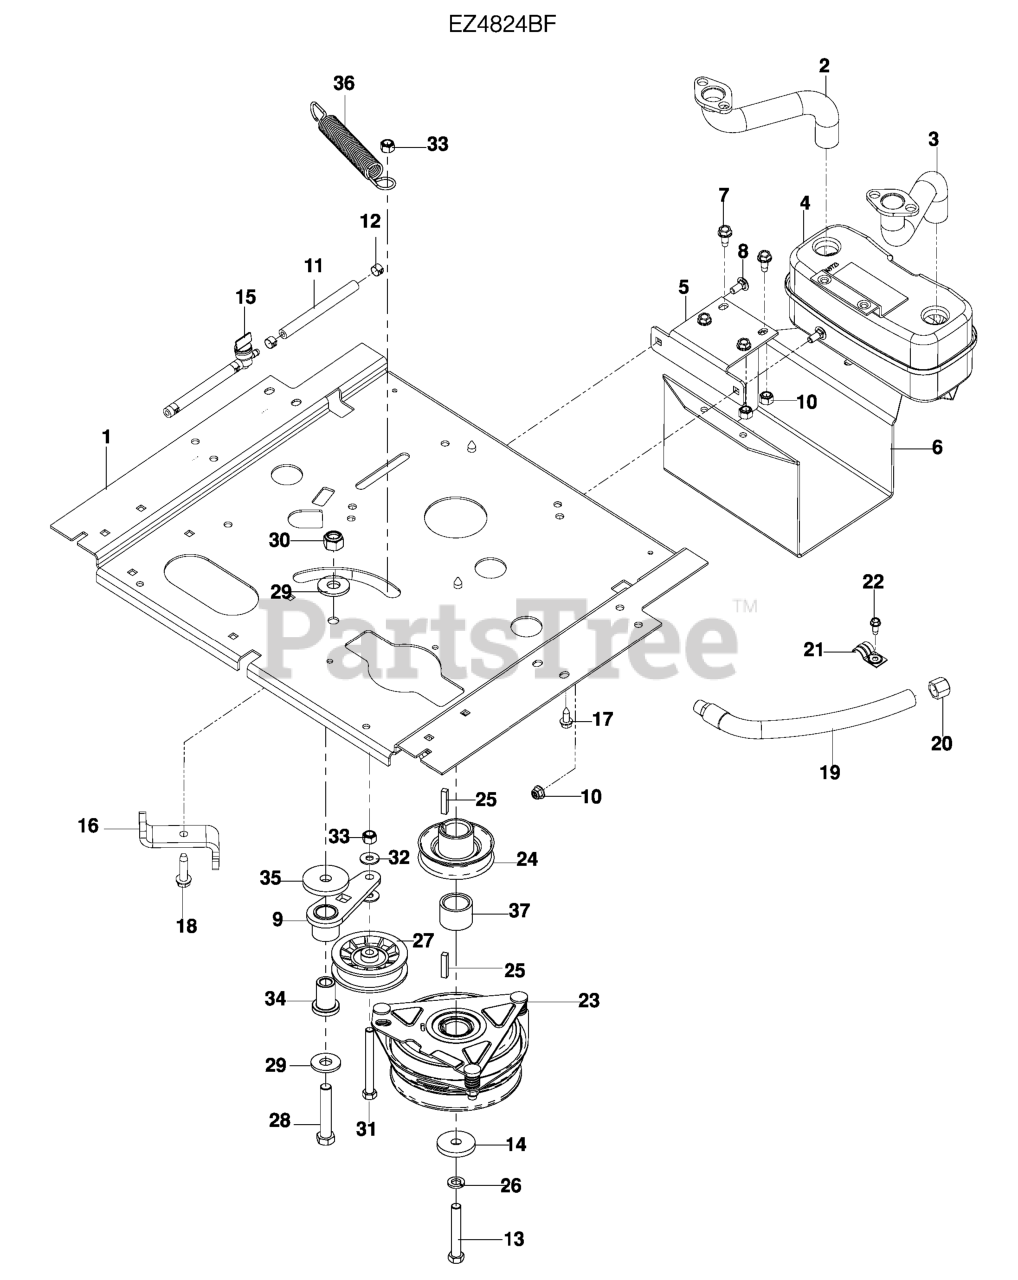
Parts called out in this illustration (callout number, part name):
1	PLATE, ENGINE, BLACK
2	RP.PIPE-EXHAUST LH
3	RP.PIPE-EXHAUST RH
4	MUFFLER ASM TWIN
5	BRACKET, MUFFLER, BLACK
6	GUARD, MUFFLER, BLACK
7	BOLT 5/16-18 X 3/4
8	BOLT 5/16C X 3/4" CARRIAGE
9	RP.IDLER ARM WELDMENT
10	5/16-18 NYLOC FLANGE NUT
11	FUEL LINE 5"
12	HOSE CLAMP
13	HCS 7/16-20 X 2-3/4
14	SPINDLE WASHER
15	FUEL VALVE
16	STOP, CLUTCH, OGURA, BLK
17	HHFS 3/8-16 X 1.0 THD FORMING
18	BOLT 3/8-16 X 1 1/2 ZINC CLEAR
19	OIL DRAIN HOSE
22	SCREW 1/4 X 5/8
23	CLUTCH, 150 FT/LBS
24	PULLEY, C'SHAFT, 3.57 OP
25	KEY, 1/4 SQ X 1 1/4
26	WASHER 7/16 LOCK
27	PULLEY, IDLER RAKE & ZTR
28	HCS 1/2C X 2 3/4
29	WASH USS FLAT 1/2
30	NUT 1/2-13 HEX NYLOC ZD
31	HCS 3/8-16X3 1/2 GR5
32	WASHER 5/16 FLAT
33	NUT 3/8-16 NYLOC
34	PIVOT, IDLER
35	HEAVY WASHER
36	SPRING, DECK DRIVE
